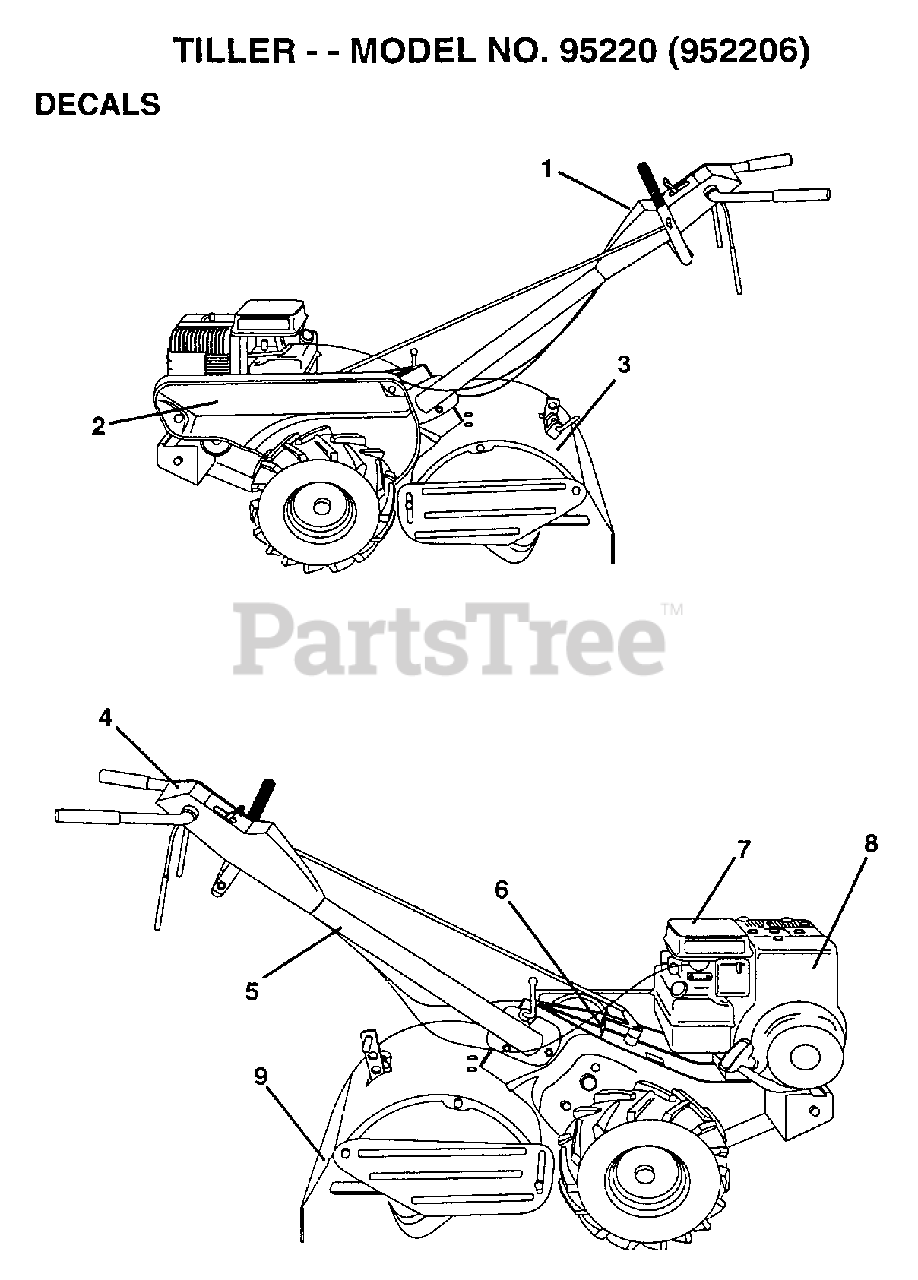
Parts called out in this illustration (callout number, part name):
1	DECAL.PNL.CONTROL
2	DECAL.LOGO.
4	DECAL.INSTRUCTION
5	DECAL TI
6	DECAL CRT
8	DECAL, BRIGGS & STRATTON
9	DECAL TI
